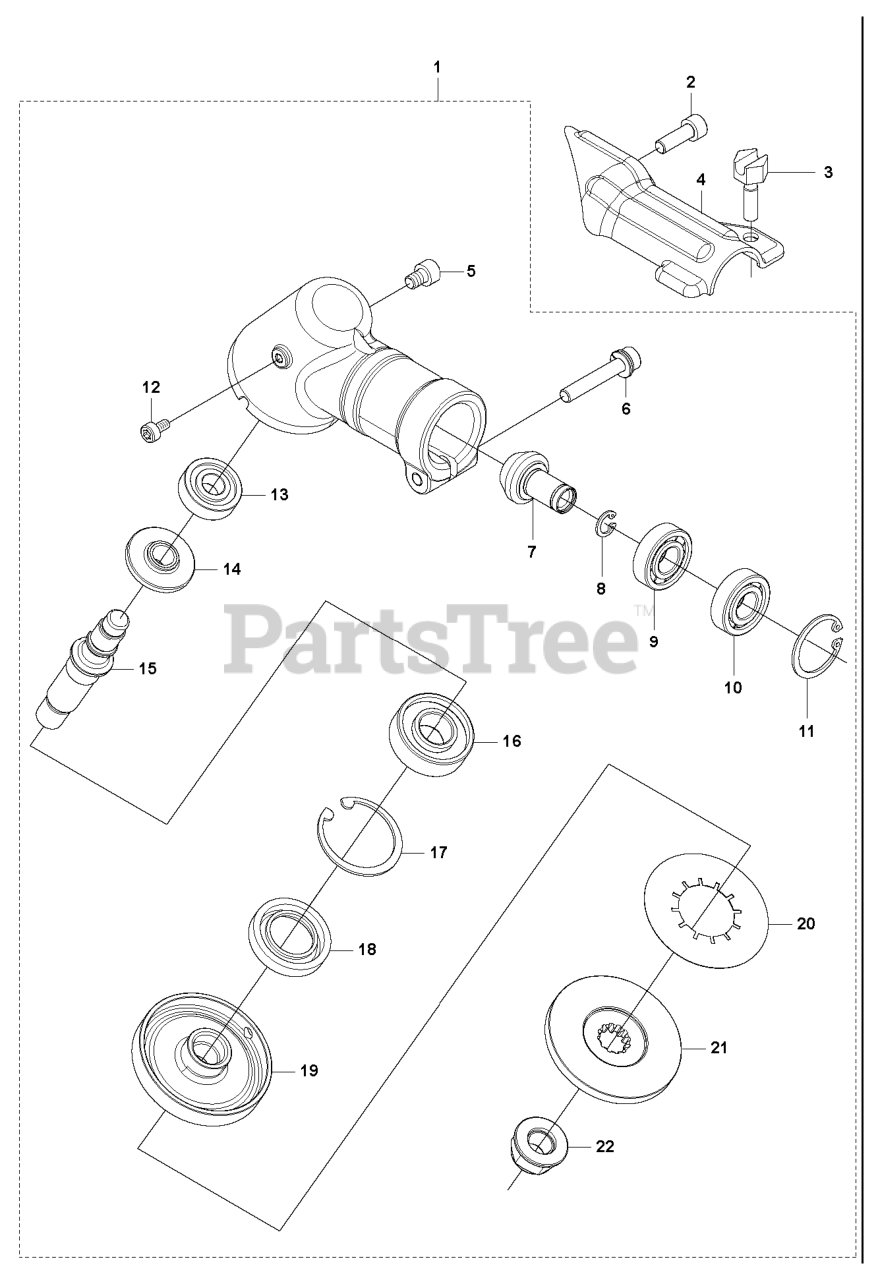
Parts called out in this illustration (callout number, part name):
2	BOLT M5X14
5	BOLT,TORX M6X8
10	BEARING,12MM ID,28MM OD, 8MM W
13	BEARING (RPLS 06000-06000)
16	BEARING 0600406202
21	HOLDER (B)
